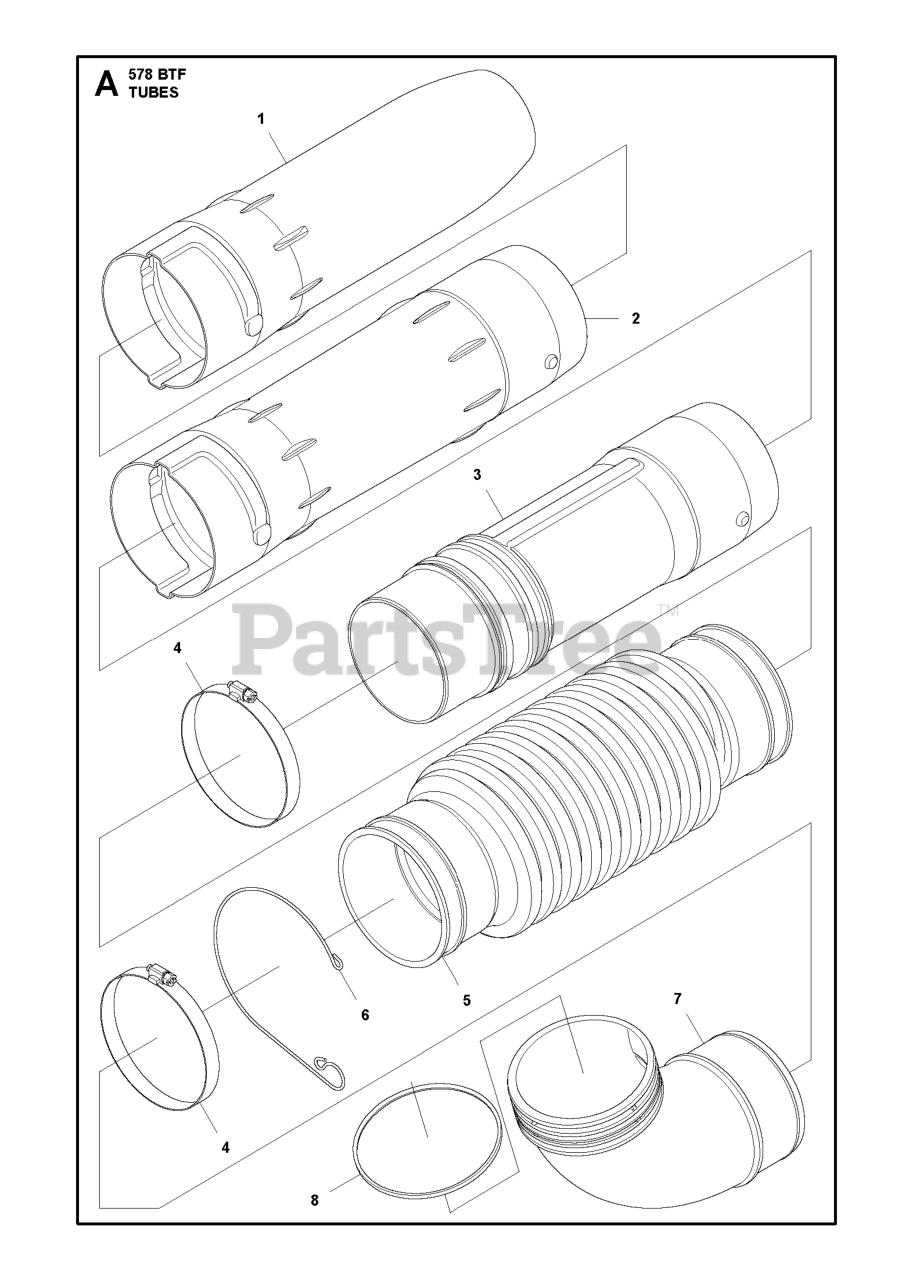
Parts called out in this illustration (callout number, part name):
2	PIPE STRAIGHT
3	SWIVEL JOINT
4	CLAMP(F115)
5	HOSE
7	PIPE ELBOW
